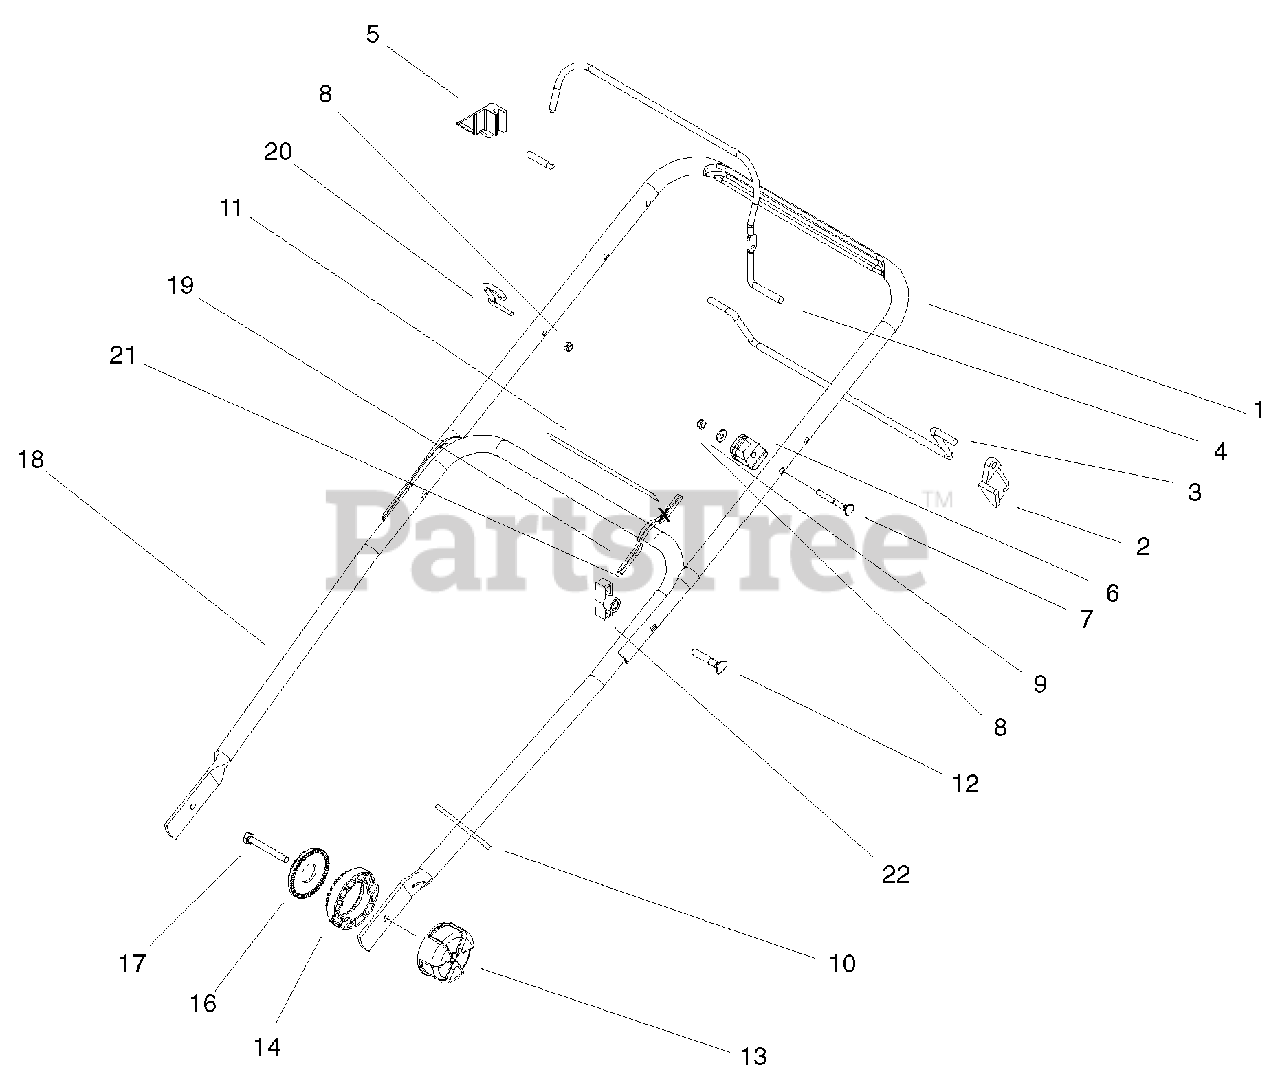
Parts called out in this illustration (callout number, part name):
1	Handle-Upper
3	Bail-Brake
4	Bail-Traction (only on: 10926)
5	Stop-Pivot (only on: 10926)
6	Anchor-Cable
7	Screw-Handle
8	Nut-Lock, NI
9	Washer-Flat
10	Tie-Cable
11	Decal-Operation (only on: 10926)
12	Screw-Handle
13	Adjusting Knob-Handle
14	Disk Adjusting-Handle
16	Disk Holding-Handle
17	Capscrew
18	Handle-Lower 7/8"
19	Cable-Brake
20	Guide-Rope
21	Cable-Traction (only on: 10926)
22	Knob-Handle
